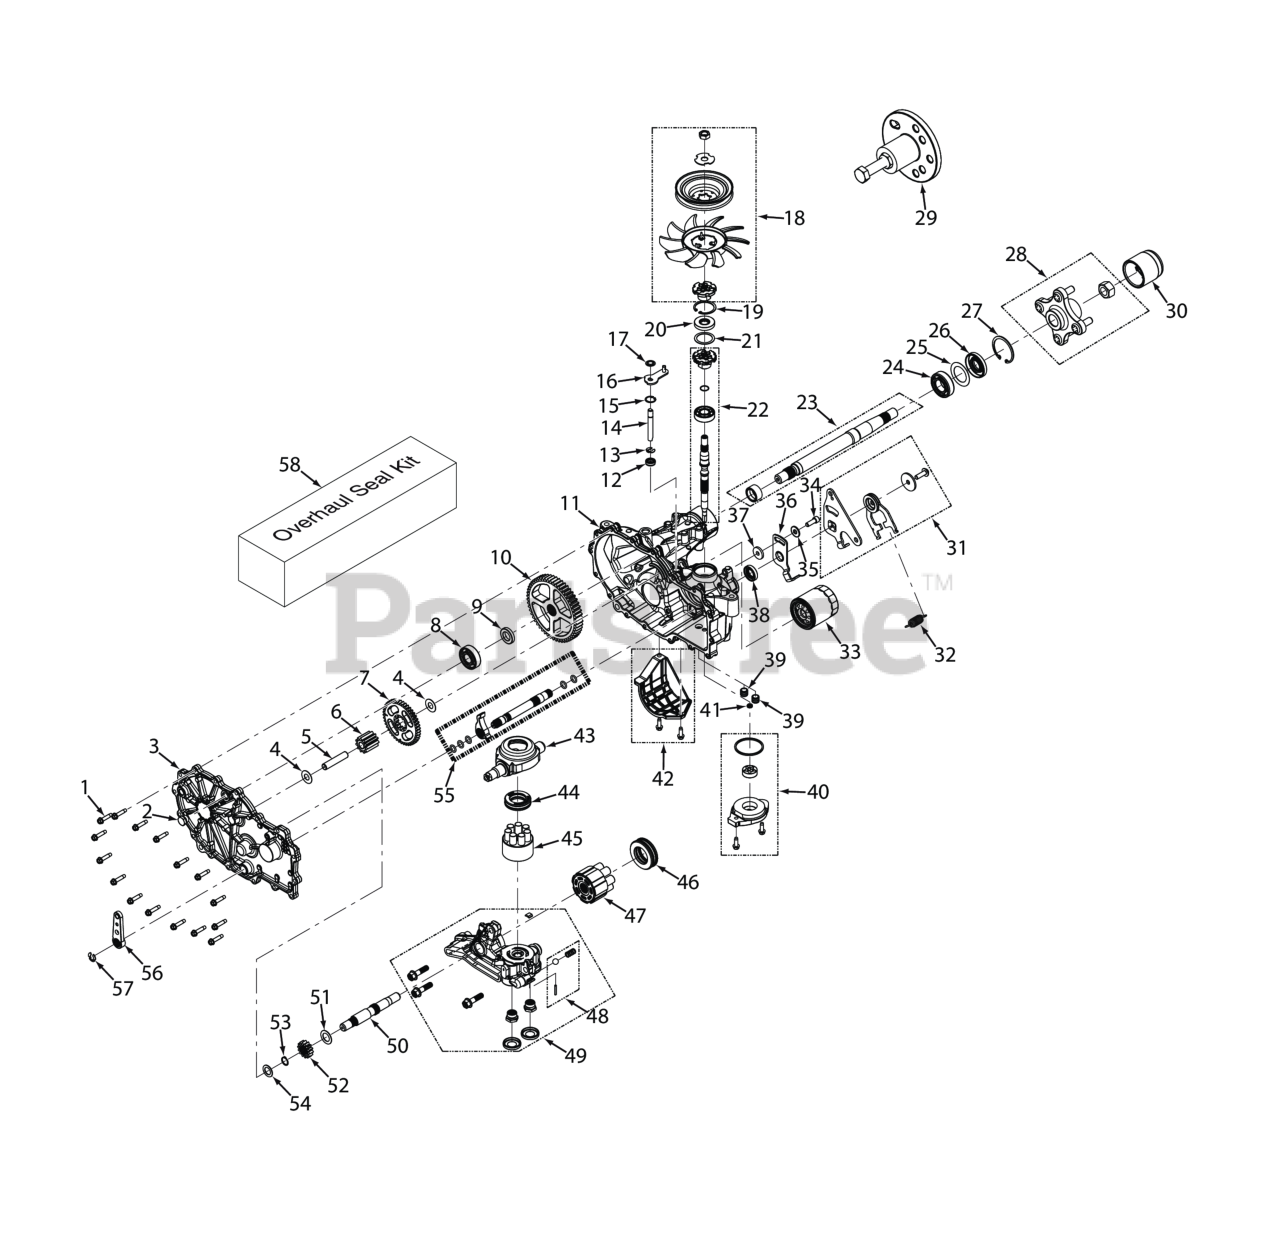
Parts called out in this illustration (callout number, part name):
1	Bolt, Hex Head 1/4-20 x 1-1/8"
2	Plug, External Hex Vent 9/16-18
3	Kit, Side Cover LH
3	Kit, Side Cover RH
4	Washer, .5 x 1.0 x .03
5	Jackshaft Pin
6	Gear, 11T
7	Gear, 45T
8	Kit, Bearing
9	Spacer, .750 x 1.320 x .257
10	Gear, 54T
11	Kit, Housing LH
11	Kit, Housing RH
12	Seal, Lip, .375 x .75 x .25
13	Ring, .Retaining .375 External
14	Rod, By-Pass
15	R i n g , Retaining .750 Internal
16	Arm, Bypass (LH)
16	Arm, Bypass (RH)
17	Ring, Retainging .375 External
18	Kit, Fan/Pulley
19	R i n g , Retaining 2.06 Internal
20	Seal, Lip 17 x 40 x 7
21	Washer, 1.23 x 1.56 x .04
22	Kit, Input Shaft
23	Kit, Shaft, Axle
24	Bearing, Ball 1.0 x 52 x 15 Open
25	Spacer, 1.355 x 2.035 x .021
26	Seal, Lip TC4 1.0 x 2.06 x .38
27	R i n g , Retaining 2.06 Internal
28	Hub Kit
29	Kit, Hub Puller
30	Cap, Axle
31	Kit, RTN Bi-Directional (Right Side)
31	Kit, RTN Bi-Directional (Left Side)
32	Spring, Extension, RTN - 44lbs
33	Filter, Oil
34	Bolt, Hex Head Cap Screw 5/16-24 x 1" Patch
35	Washer, 7/16 x 7/8 OD x .06 HT
36	Arm, Neutral (Left Side)
36	Arm, Neutral (Right Side)
37	Spacer, .32 ID x 1.005 OD x .1495 Thk
38	Seal, Lip 18 x 32 x 7
39	Tube, Charge Triple O-ring
40	Kit, Charge Pump
41	Kit, Gerotor Seal
42	Kit, Filter Guard (LH)
42	Kit, Filter Guard (RH)
43	Trunnion, Swashplate
44	Ball Thrust Bearing
45	Kit, Cylinder Block
46	Thrust Ball Bearing Assembly
47	Kit, 16cc Cylinder Block Assembly (steam
48	Kit, Charge Relief
49	Kit, Charge Relief
49	Kit, Center Section, LH Charge
50	Shaft, Motor
51	Washer, .72 x 1.16 x .04
52	Washer, Flat, .71 x 1.16 x .04
53	Ring, Retaining .625
54	Washer, HT .62 ID x 1.0 OD x .05 Thick
55	Kit, Inboard, RH Rot B / LH Rot A (LH)
55	Kit, Inboard, RH Rot A / LH Rot B (RH)
56	Handle, Brake
57	Ring, Retaining External .375"
58	Kit, Outboard, RH Rot A / LH Rot B (RH)
59	Tube, Sealant
